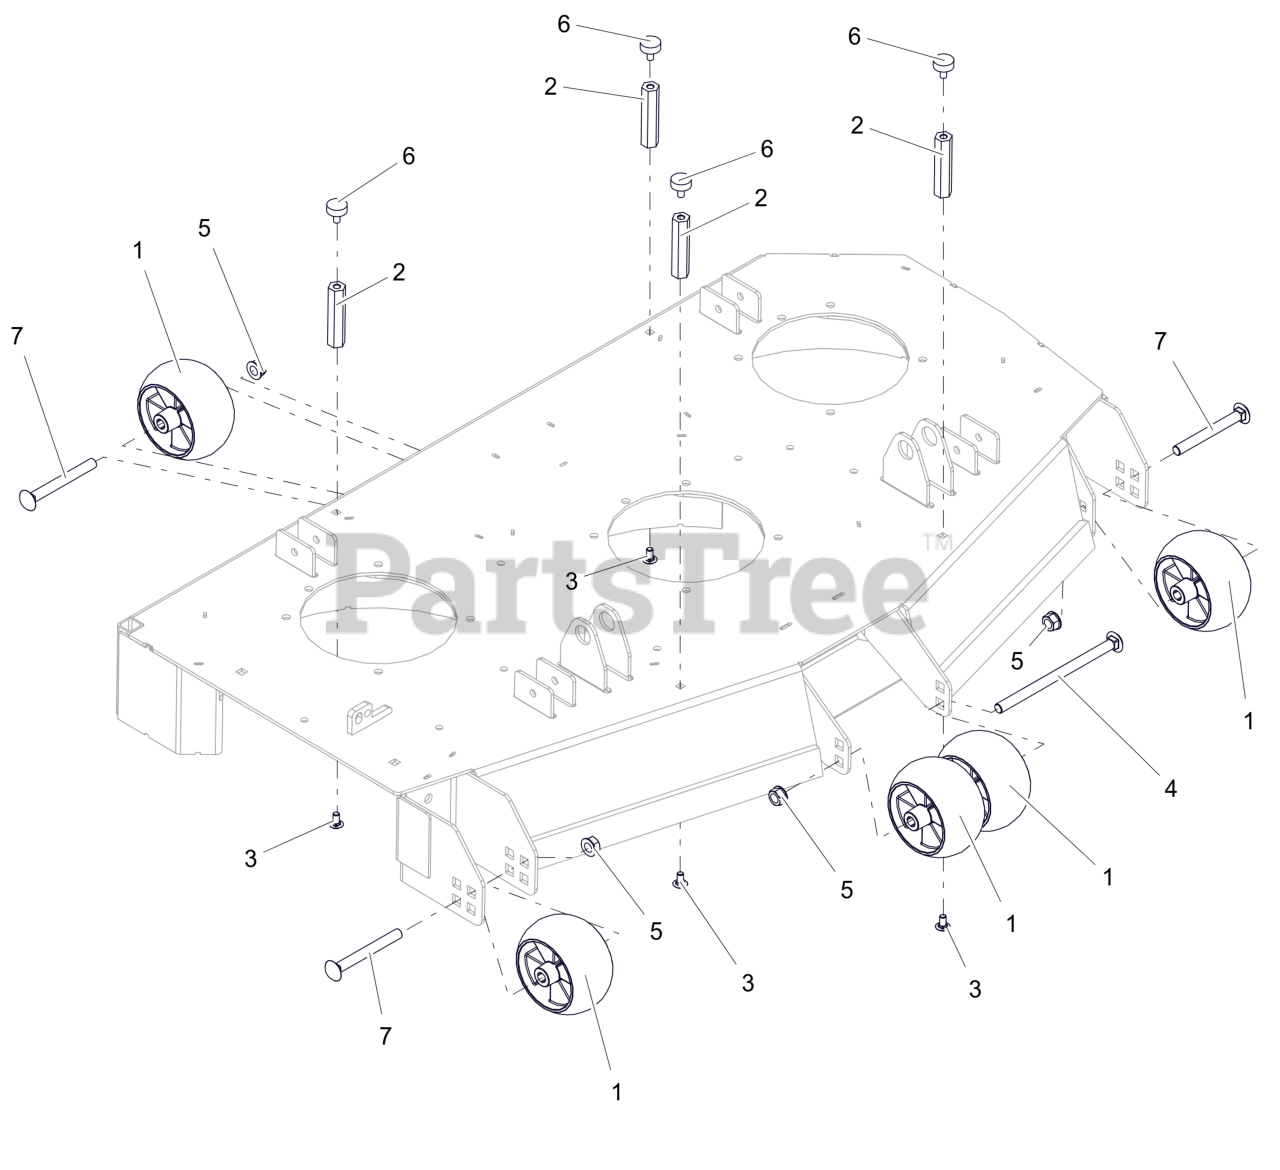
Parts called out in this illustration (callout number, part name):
1	WHEEL, ANTI SCALP - 5X3 CTR W/RIBS
2	NUT, COUPLING .312-18 X 3.375
3	BLT,RHSSN.31-18X.625 G5 ZCCP30
4	BTL,RHSN .500-13 X 8 G5 ZCC
5	NUT-LK-CTR-FLG .500-13 GG ZCC
6	BUMPER, RUBBER
7	BLT,RHSN .50-13X4.50 G5 ZCC
